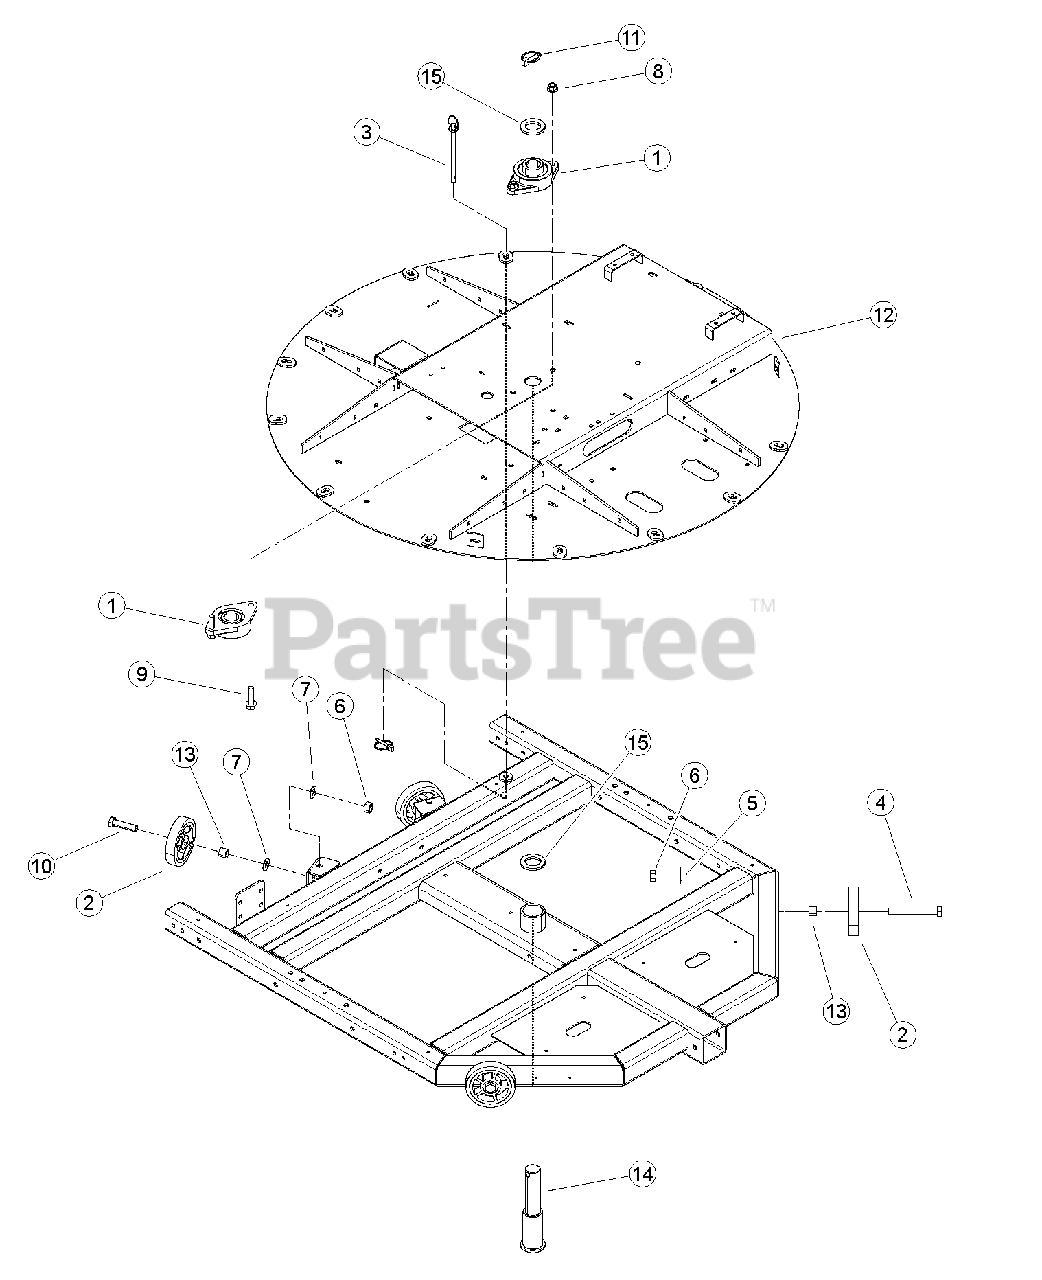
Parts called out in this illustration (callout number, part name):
1	BEARING, 1-1/2" 2-BOLT SET SCREW
2	ROLLER, 5 X 1 X 5/8 NOFF AL
3	PIN, HITCH 1/2 X 6-1/2 W LYNCH
4	BOLT, 5/8 X 5 HEX HD G5 ZP
5	WASHER, 5/8" FLAT ZP
6	NUT, 5/8" CENTERLOCK ZP GR5
7	WASHER, 5/8" SAE FLAT ZP
8	NUT, 1/2-13 NYLOCK FLANGE
9	BOLT, 1/2-13 X 2 HWH GR5 CZP
10	BOLT, 5/8 X 2-1/2 HEX HD GR5 ZP
11	PIN, 7/16 X 1-3/4 LYNCH
12	WELDMENT, CHIPPER BASE
13	SPACER, 7/8 X 3/4
14	PIN, CHIPPER PIVOT
15	SPACER, 2.00 X 1.50 X 0.25
